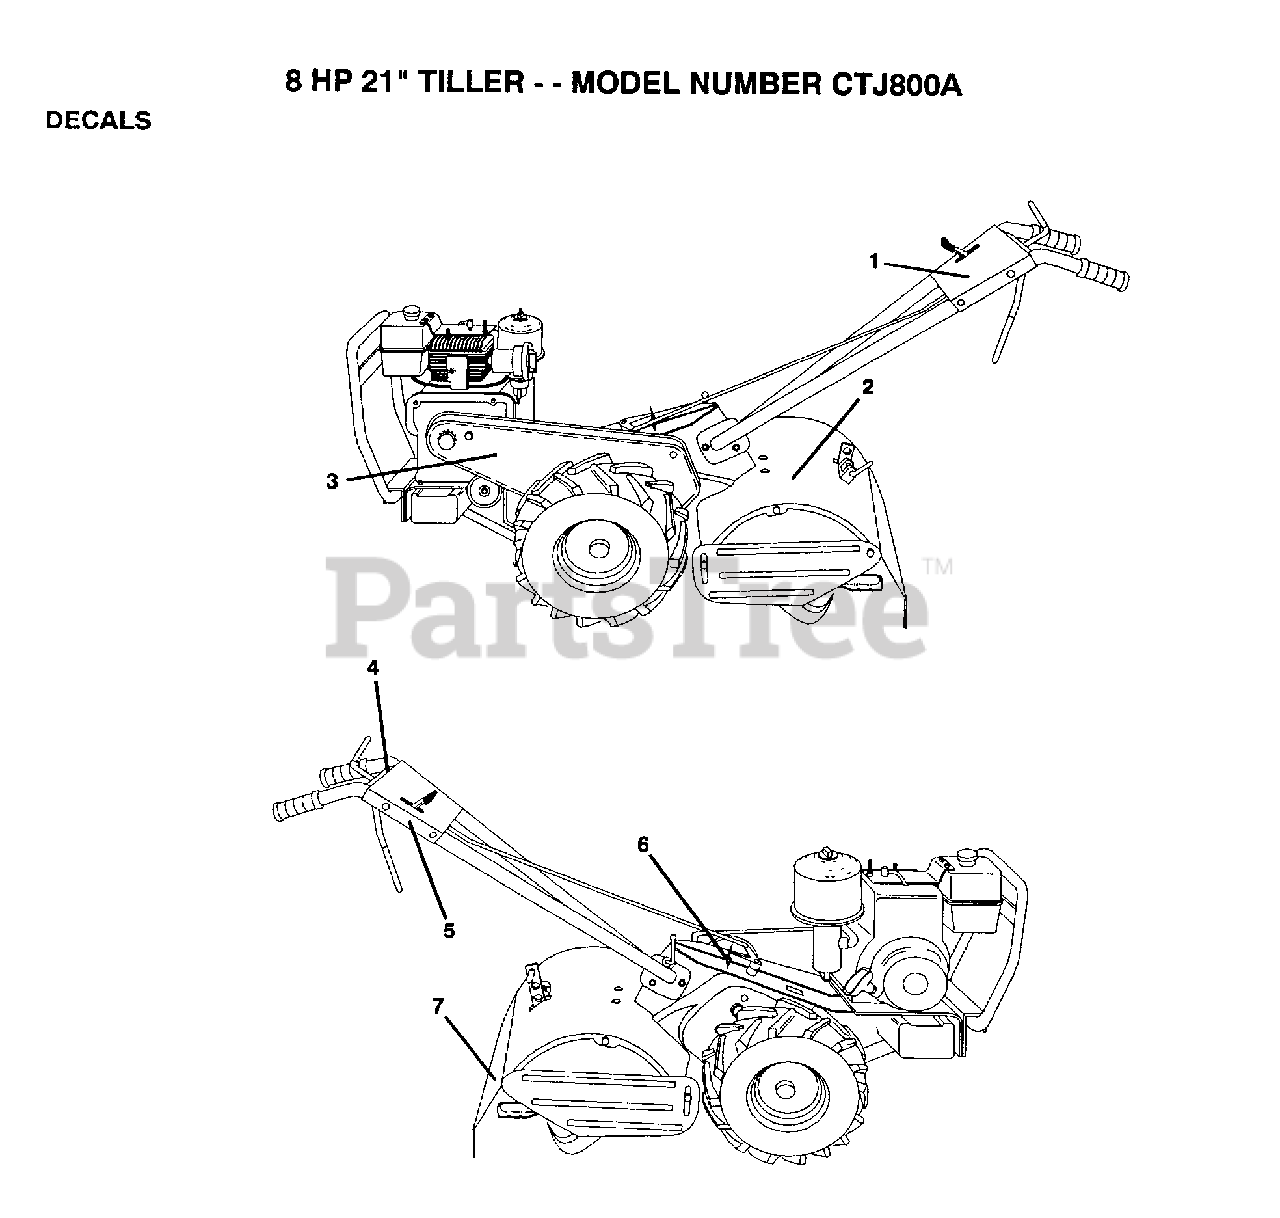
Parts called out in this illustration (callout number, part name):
1	DECAL.CNTL.PNL
3	DECAL.GUARD.BELT
5	DECAL TI
6	DECAL, SHIFT INDICATOR
7	DECAL TI
